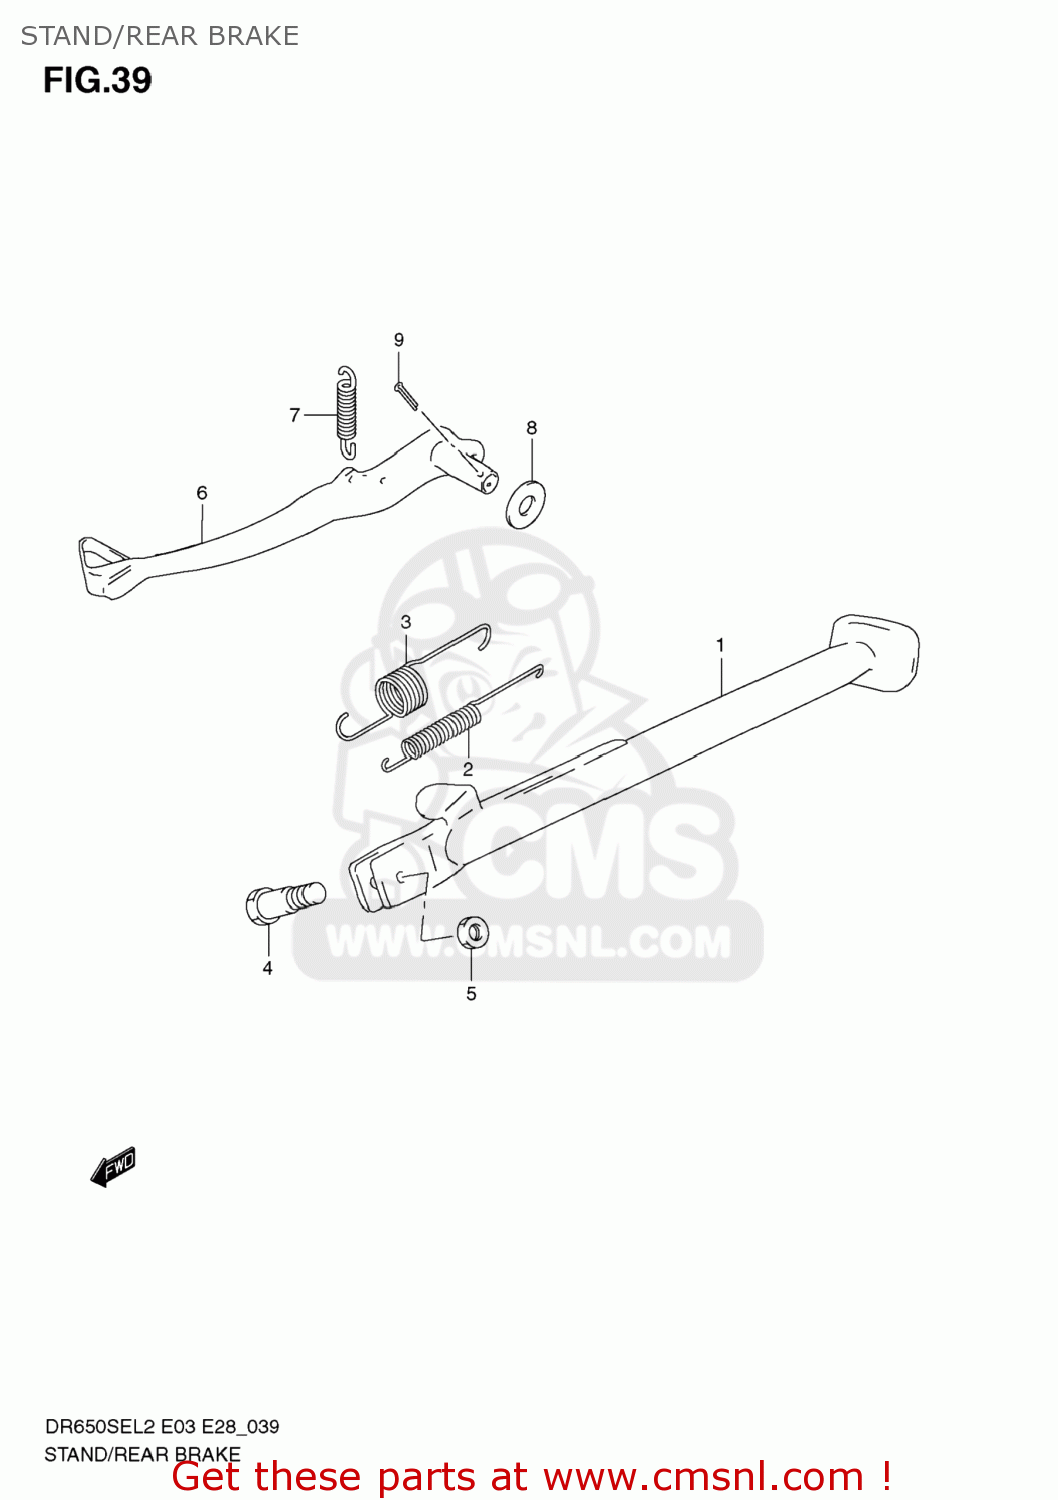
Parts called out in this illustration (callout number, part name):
1	STAND,PROP
2	SPRING
3	SPRING
4	BOLT(10X30)
5	NUT
6	PEDAL,BRAKE
7	SPRING
8	WASHER(15.5X24X2.3)
9	PIN
